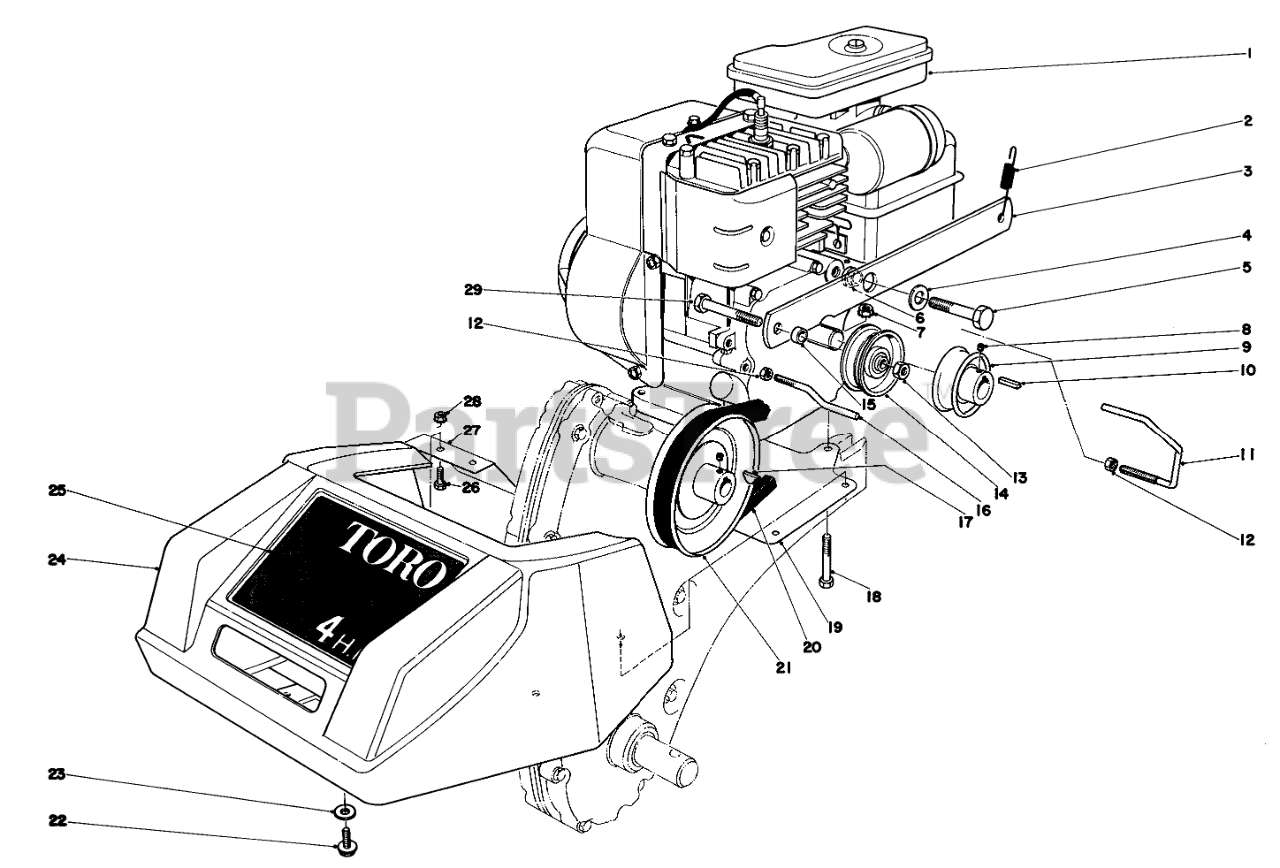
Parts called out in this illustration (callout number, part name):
1	Engine
2	TENSION SPRING
3	Idler Arm
4	WASHER-FLAT
5	SCREW-HH
6	Spacer Idler Arm
7	NUT-KEPS
8	SCREW-HSH
9	Driver Pulley
10	KEY-SQUARE
11	Belt Guide
12	NUT-HEX
13	NUT-LOCK, CONE
14	PULLEY-IDLER
15	Spacer
16	Belt Guide
17	KEY-WOODRUFF
18	SCREW-HH
19	Mounting Plate Shield
20	V-Belt
21	Driver Pulley
22	Screw
23	WASHER-PLAIN
24	Shroud
25	Decal 4 H.P.
26	SCREW-HH
27	Shield
28	NUT-HEX, SIDE DEFORM
29	SCREW-HH
